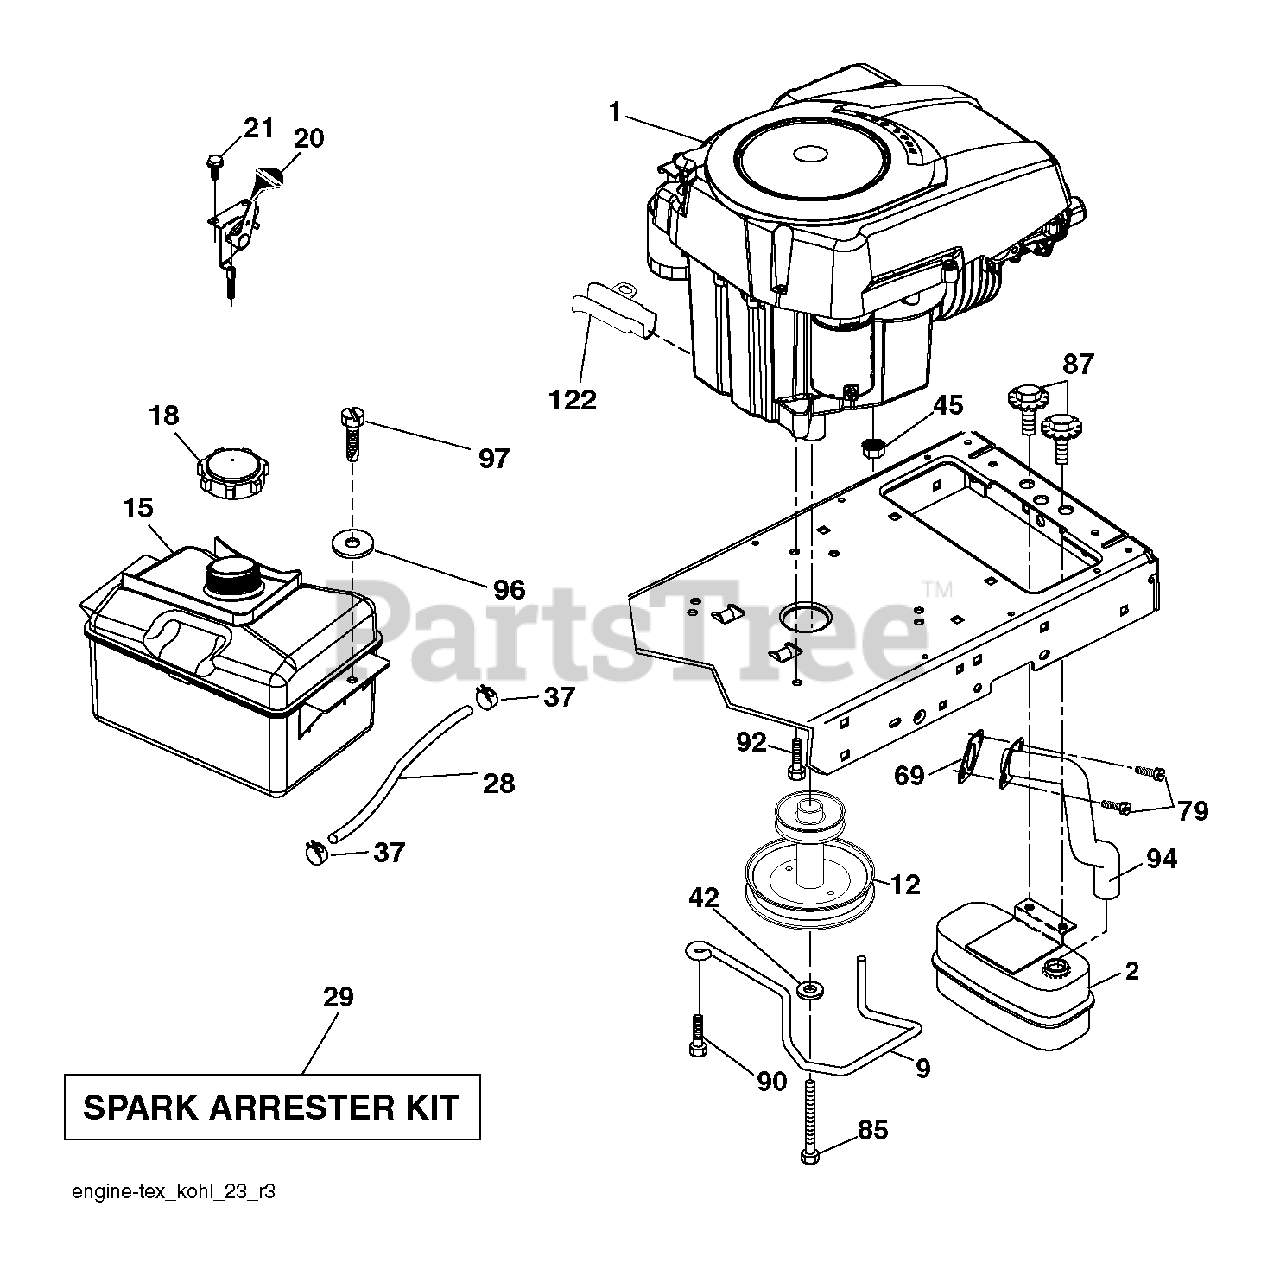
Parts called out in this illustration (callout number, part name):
2	MUFFLER.SINGLE.CYL.KOHL/B&S
9	KEEPER.BELT.ENGINE.3.25 (3 2)
12	PULLEY ENGINE
15	FUEL.TANK.ASM.NON-EPA
18	CAP ASM.FUEL.2.25"FR.
20	CONTROL.TH/CK.C.
21	SCREW.#10 X 0.750.BOS
28	LINE.FUEL.20
29	KIT.SPARK ARRESTOR 794945 B&S
37	HOSE CLAMP
42	LOCKWASHER
45	NUT
69	GASKET.EXHAUST.KOHLER
79	SCREW.SOCKET HD.5/16-1
85	BOLT HEX 7/16-20X4-1/4"
87	BOLT, 5/16-18 X 1 3/4
90	SCREW 3/8-16X1
92	SCREW 3/8-16X1
94	RP.TUBE.EXHAUST.KOHL.COURAGE
97	SCREW HEXWSHR 1/4-20X3/4
122	EXTENSION DRAIN OIL
